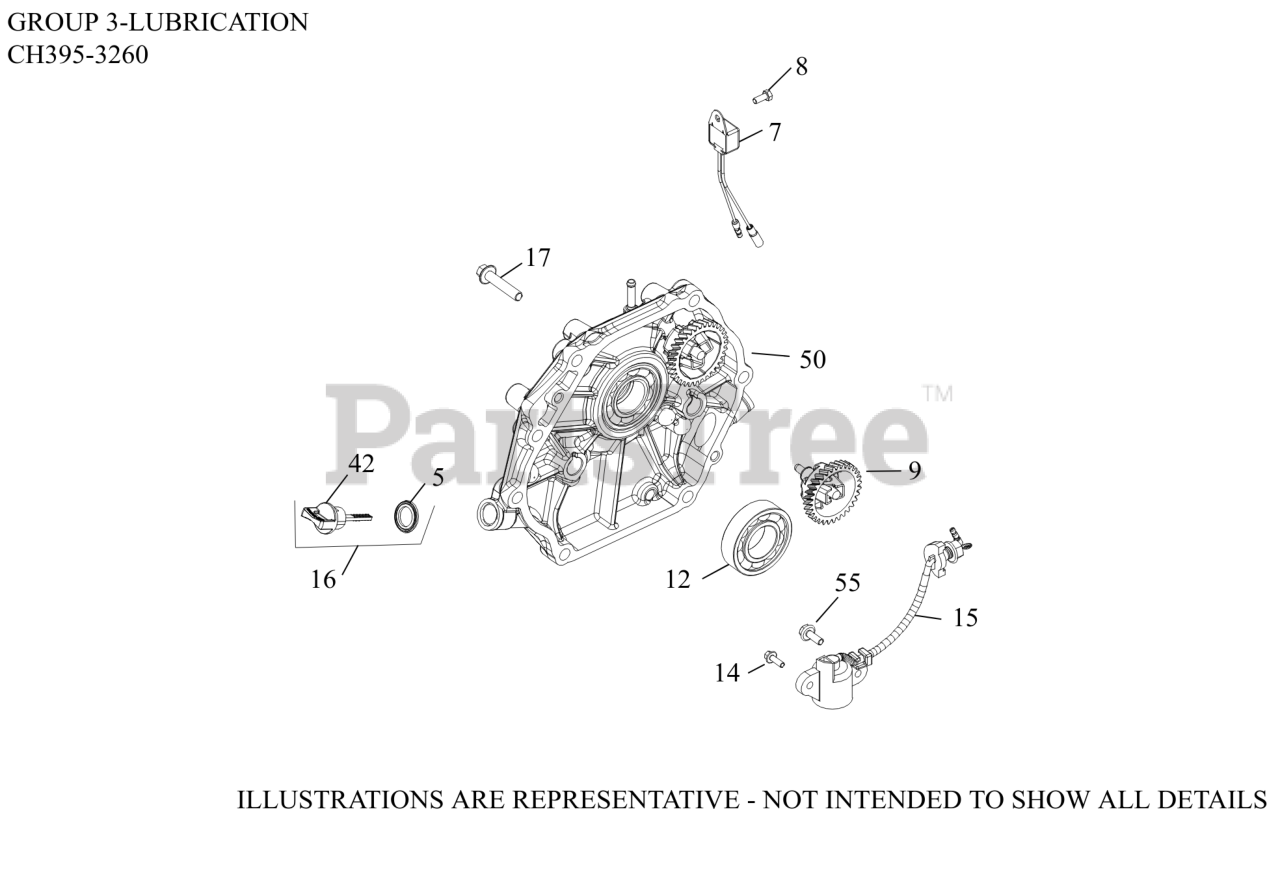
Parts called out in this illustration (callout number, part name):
5	GASKET, DIPSTICK
7	CONTROL, OIL ALERT UNIT
8	SCREW, HEX/PHILLIPS M5
9	GOVERNOR, ASSEMBLY
12	BEARING, CRANKSHAFT
14	SCREW, M6 X18
15	SWITCH, OIL SENSOR ASSEMBLY
16	DIPSTICK ASSEMBLY
17	SCREW, CLOSURE PLATE
42	DIPSTICK - USE 17 038 08-S
50	PLATE, CLOSURE & BEARING
55	SCREW, M6 X 16
